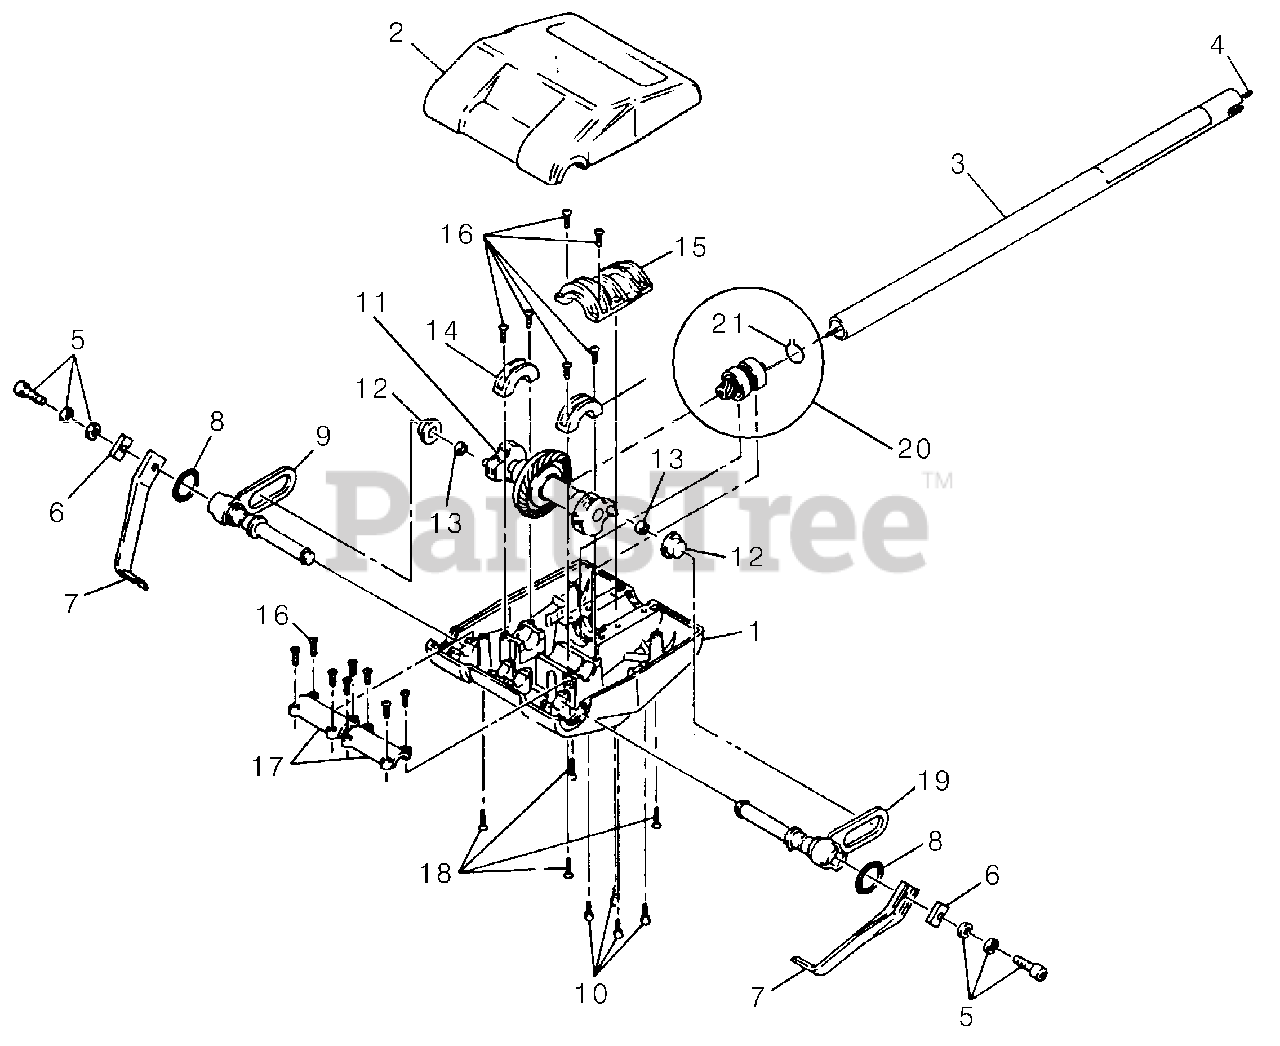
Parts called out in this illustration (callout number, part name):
1	LOWER COVER
2	UPPER HOUSING
3	DRIVESHAFT HOUSING
4	FLEX CABLE
5	BOLT-Sems (1/4 - 28 x 1")
6	SUPPORT-Tine
8	"O" RING
9	ROCKER ARM (L.H.)
10	SCREW, Thread Form (10-24 x 3/4")
11	CRANK ASSY.
12	FLOATING BUSHING
13	WASHER
14	CRANKSHAFT CLAMP
15	SHAFT CLAMP
16	SCREW, Thread Form (10-24 x 3/4")
17	SHAFT CLAMP
18	SCREW (8-16 x 1")
19	ROCKER ARM (R.H.)
20	PINNON GEAR & BEARING
21	SNAP RING
